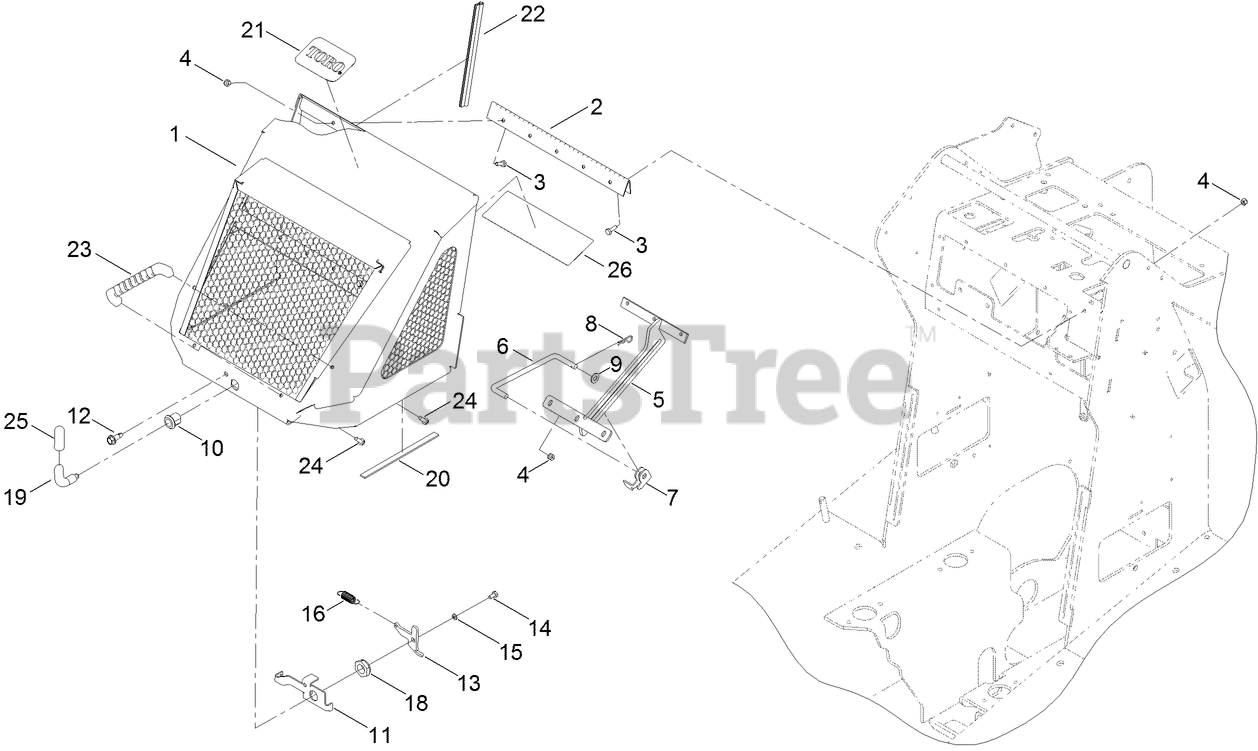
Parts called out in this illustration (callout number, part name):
1	ENGINE HOOD ASM
2	HINGE-HOOD
3	SCREW-HH
4	NUT-LOCK, NI
5	BRACKET-PROP, HOOD
6	ROD-SUPPORT, HOOD
7	BRACKET-LATCH, LOCKING
8	PIN-COTTER
9	WASHER-FLAT
10	HOUSING-LATCH
11	BRACKET-LATCH
12	SCREW-TAPPING
13	CAM-HOOKED
14	SCREW-HH
15	WASHER-LOCK
16	SPRING
18	NUT-LOCK, NI
19	HANDLE-LATCH
20	STRIP-FOAM
22	TRIM-SEAL, BULB
23	HANDLE-DOOR
24	SCREW-HWH
25	GRIP-LEVER, HOOD
26	DECAL-SERVICE TX1000 DE
26	DECAL-SERVICE TX1000 ES
26	DECAL-SERVICE TX1000 FR
26	DECAL-SERVICE TX1000 IT
26	DECAL-SERVICE TX1000 NE
26	DECAL-SERVICE TX1000 PL
26	DECAL-SERVICE TX1000 RU
26	DECAL-SERVICE TX1000 SK
26	DECAL, SERVICE TX1000
